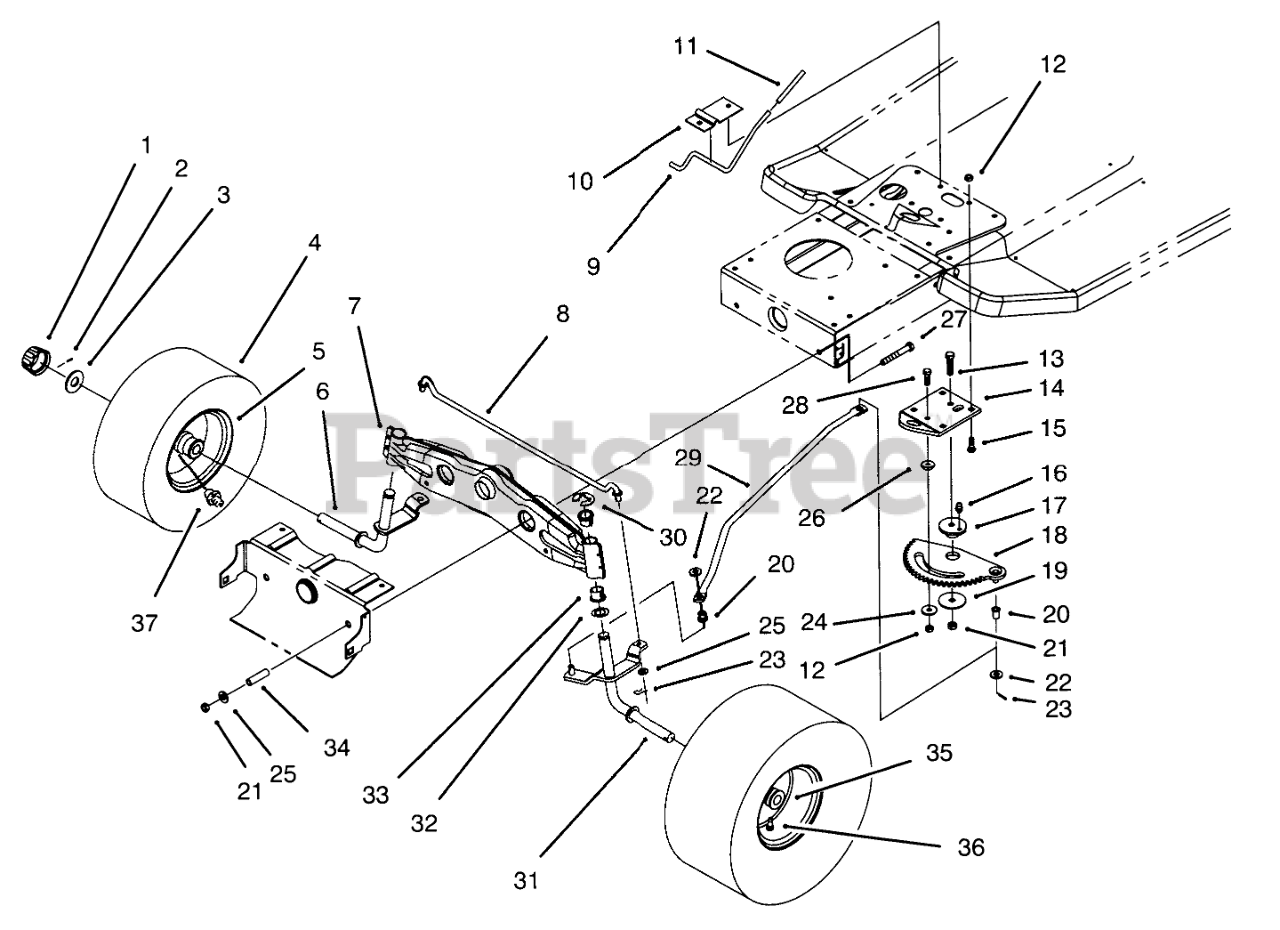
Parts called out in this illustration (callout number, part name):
1	CAP-HUB
2	PIN-COTTER
3	WASHER-PLAIN
4	TIRE 13 X 5.00 X 6
5	RIM ASM
6	Spindle-R.H.
7	Axle-Front
8	TIE ROD-STEERING
9	ROD-BRAKE, PARKING
10	Bracket-Parking Brake
11	GRIP-BRAKE, PARKING
12	NUT-LOCK, NI
13	SCREW-CARR
14	Bracket-Steering Rack
15	BOLT-CARR
16	FITTING-GREASE
17	BUSHING-ECCENTRIC
18	RACK-STEERING
19	WASHER-BEARING
20	BUSHING-FLANGED, NYLON
21	NUT-LOCK, NI
22	WASHER-FLAT
23	PIN-COTTER
24	WASHER-PIVOT
25	WASHER-FLAT
26	SPACER-RACK, STEERING
27	SCREW-HH
28	SCREW-CARR
29	LINK-DRAG
30	E-RING
31	Spindle-L.H.
32	WASHER-THRUST
33	BUSHING
34	SPACER
35	BEARING-WHEEL
36	STEM-VALVE
37	FITTING-GREASE
